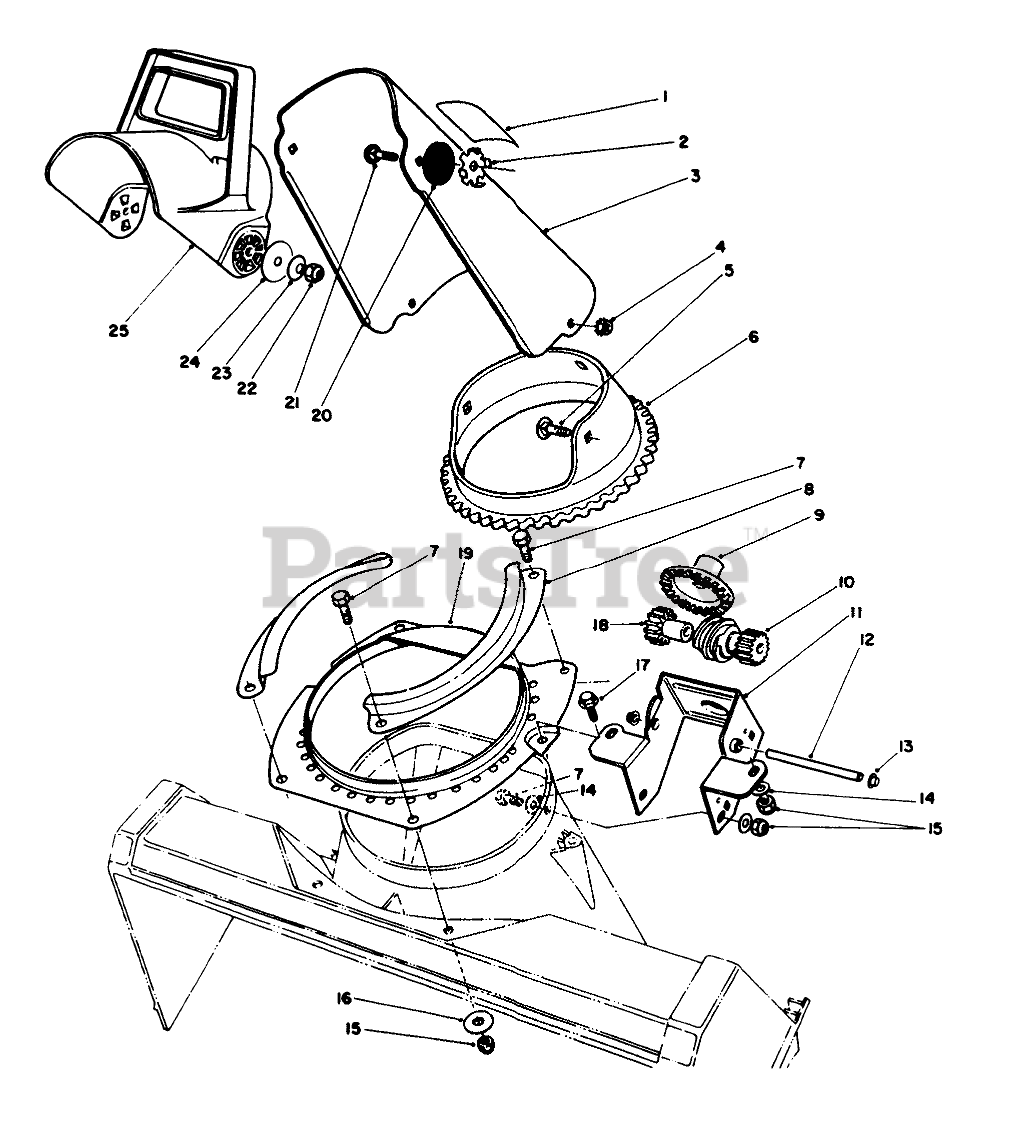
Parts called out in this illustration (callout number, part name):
1	Decal-Danger
2	PLATE-FRICTION
3	Chute-Discharge (Incl. Ref. #1: 63-3760)
4	NUT-KEPS
5	SCREW-CARR
6	RING-GEAR, CHUTE
7	SCREW-HH
8	Retainer-Chute Ring
9	GEAR-FACE
10	GEAR-SPUR/WORM
11	Bracket-Chute Gear
12	SHAFT-GEAR, WORM
13	NUT-PUSH
14	WASHER-FLAT
15	NUT-LOCK, NI
16	WASHER-FLAT
17	SCREW-PLASTITE
18	GEAR-SPUR, SPACER
19	Ring-Chute Support
20	WASHER-RUBBER
21	SCREW-CARR
22	NUT-LOCK, NI
23	WASHER-BELLEVILLE
24	WASHER-FLAT
25	CHUTE-DEFLECTOR
